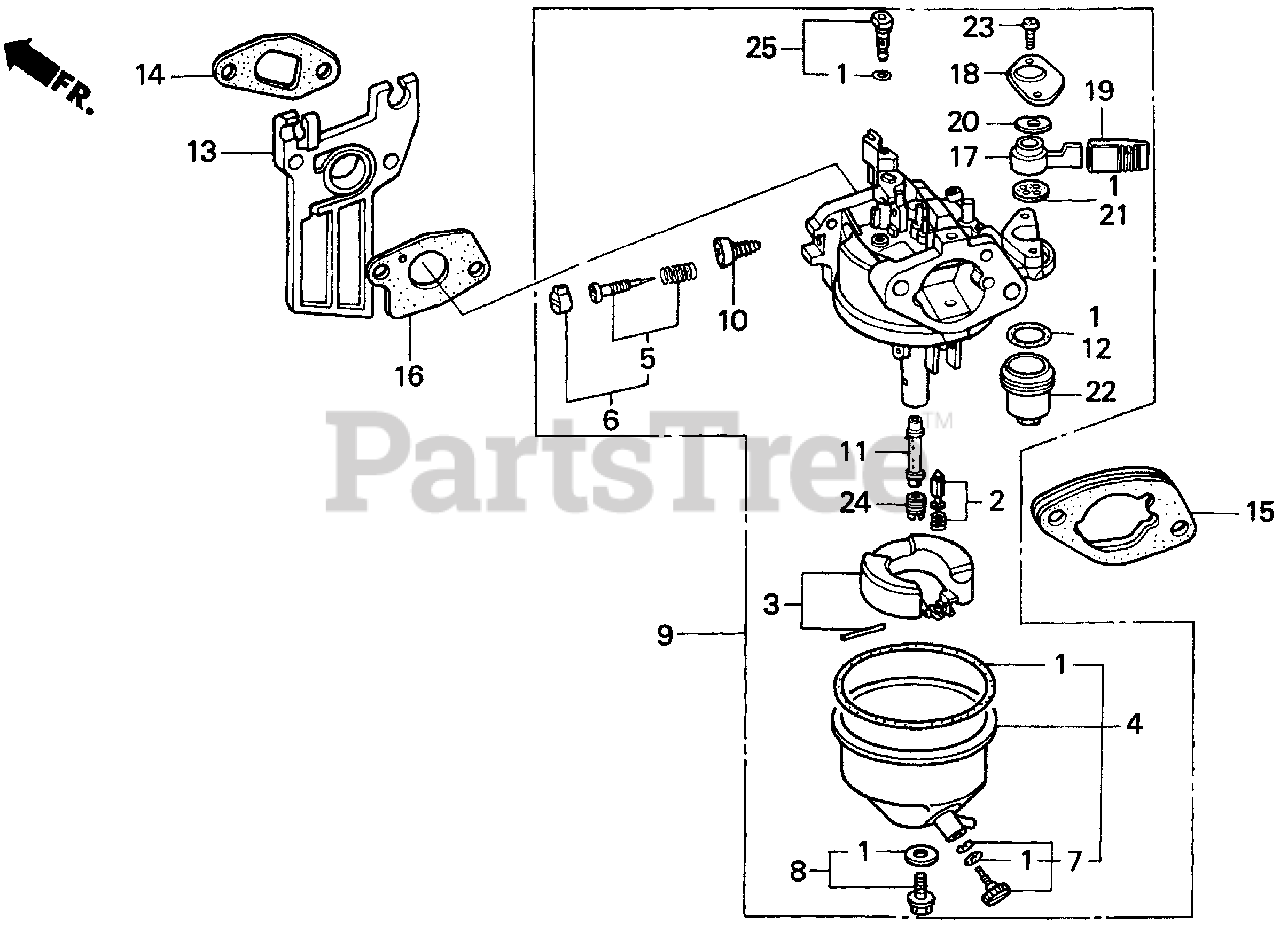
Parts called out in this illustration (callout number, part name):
1	GASKET SET
2	VALVE SET, FLOAT (SEAT NOT INCLUDED)
4	CHAMBER SET, FLOAT
5	SCREW SET, PILOT
7	SCREW SET, DRAIN
8	SCREW SET
9	CARBURETOR ASSY. (BE07B C)
9	CARBURETOR ASSY. (BE07B D)
10	SCREW, THROTTLE STOP
11	NOZZLE, MAIN
12	GASKET, FUEL STRAINER CUP
13	INSULATOR, CARBURETOR
14	GASKET, INSULATOR
15	SPACER, CARBURETOR
16	GASKET, CARBURETOR
17	LEVER, PETCOCK
18	PLATE, LEVER SETTING
19	CAP, LEVER
20	SPRING, PETCOCK LEVER
21	GASKET, PETCOCK
22	CUP, FUEL STRAINER
23	SCREW, PAN (3X6)
23	SCREW, PAN (3X8)
24	JET, MAIN (#72)
24	JET, MAIN (#75)
24	JET, MAIN (#70)
25	JET SET, PILOT (#35)
